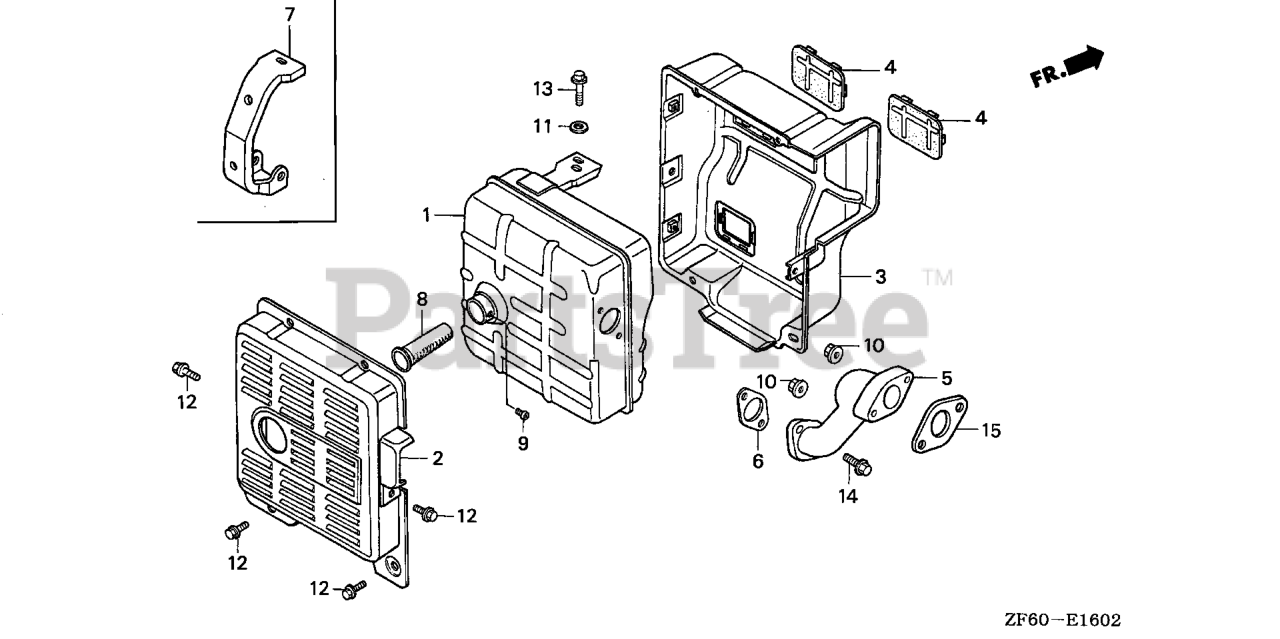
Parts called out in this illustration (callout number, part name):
1	MUFFLER (TSURUMI)
2	PROTECTOR, MUFFLER (OUTER)
3	PROTECTOR, MUFFLER (INNER)
4	SEAL, MUFFLER PROTECTOR
6	GASKET, EX. PIPE
7	STAY A, MUFFLER (TSURUMI)
8	ARRESTER, SPARK
9	SCREW, TAPPING (4X8)
10	NUT, FLANGE (8MM)
12	BOLT, FLANGE (6X12) Use up to Engine SN 1543277.
14	BOLT, FLANGE (8X20) Use up to Engine SN 1609606.
15	GASKET, EX. PIPE Use up to Engine SN 2949254.
15	GASKET, EX. PIPE (WACKER)
